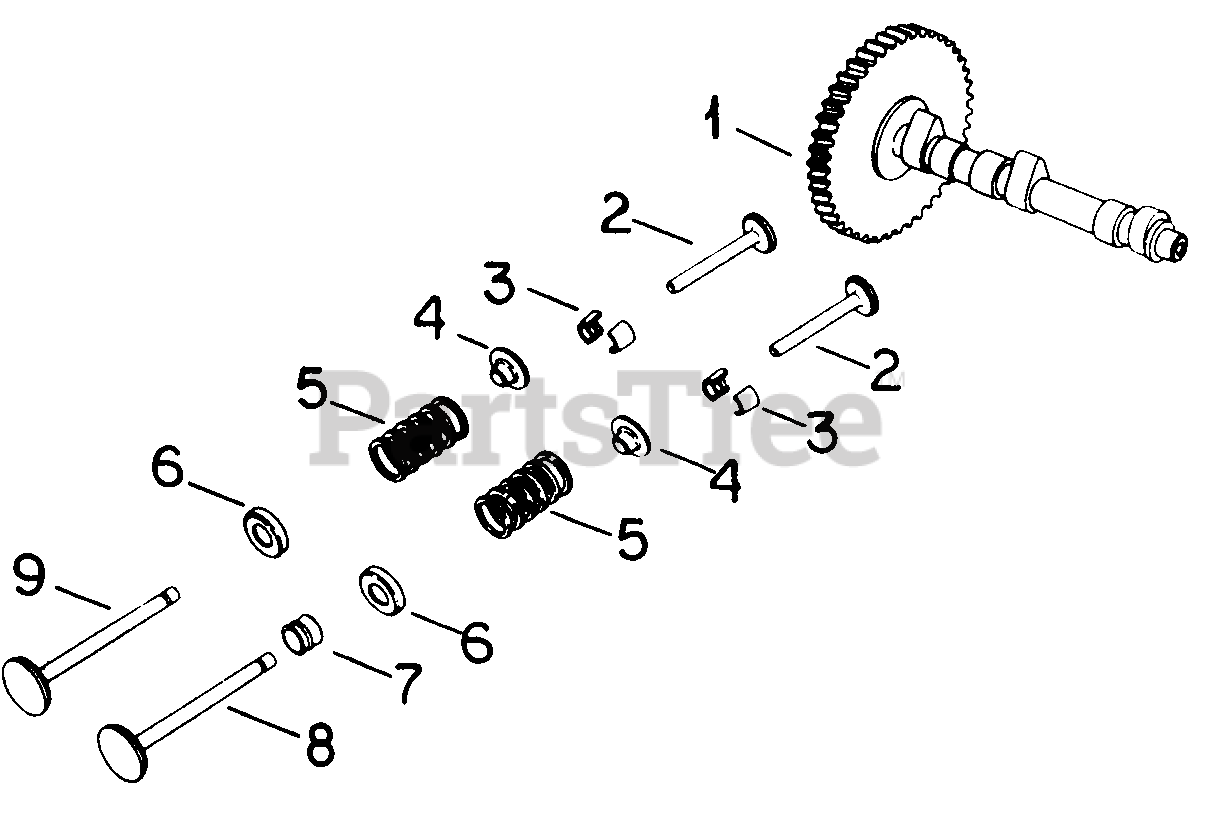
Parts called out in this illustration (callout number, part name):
1	Camshaft w/Gear Assy
2	Tappet, Valve
3	Kit, Retainer Keeper Valve
4	Retainer, Spring
5	Spring, Valve
6	Retainer, Spring
7	Seal, Valve Stem
8	Valve, Intake
9	Valve, Exhaust
